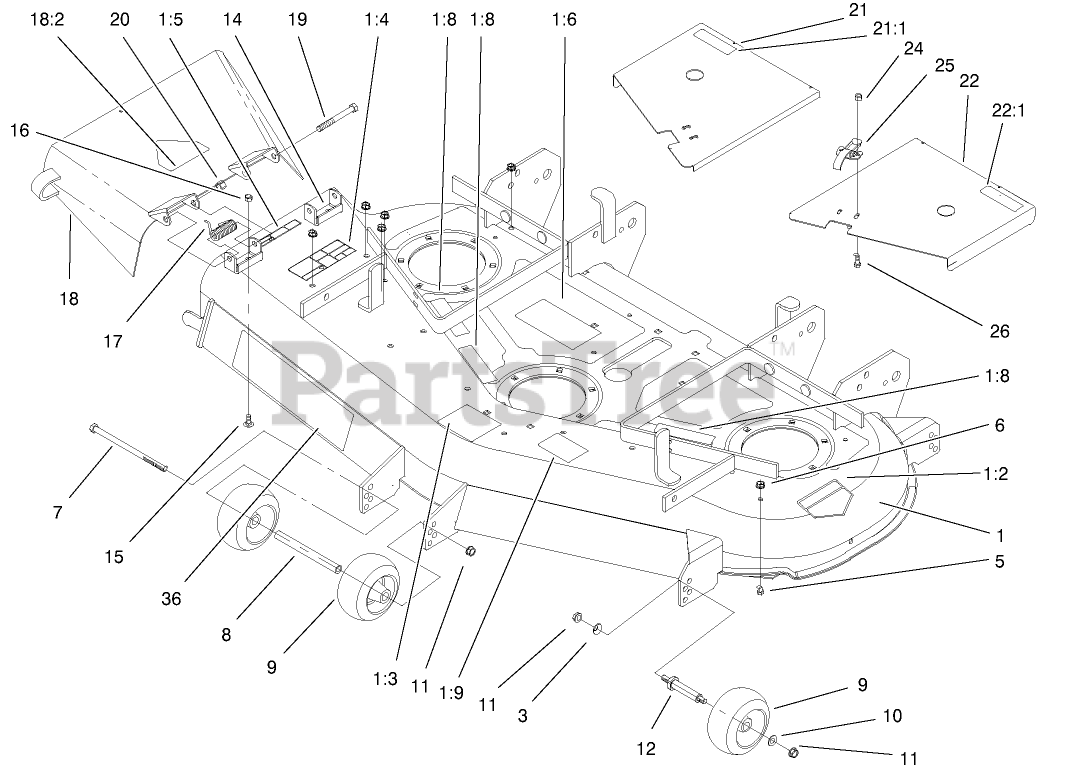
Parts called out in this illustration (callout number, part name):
1	52" Deck ASM
1:2	DECAL-DANGER
1:3	DECAL-WHEEL, GAGE
1:4	DECAL-DANGER, THROWN OBJECT
1:5	DECAL-DANGER
1:6	DECAL-BELT ROUTING
1:8	DECAL-COVER, MISSING
1:9	DECAL-TORQUE, BLADE BOLT
3	WASHER-BELLEVILLE
5	SCREW-HH
6	NUT-HF
7	SCREW-HH
8	SPACER-WHEEL
9	WHEEL-GAGE
10	Washer
11	NUT-HHF, WHIZ
12	SPACER
14	BRACKET-PIVOT
15	SCREW-CARR
16	NUT-LOCK, CONE
17	SPRING
18	DEFLECTOR ASM, 52" W/DECAL
18:2	DECAL-DANGER
19	SCREW-HH
20	NUT-HEX
21	COVER ASM-RH
21:1	DECAL-DANGER
22	LH COVER ASM
22:1	DECAL-DANGER
24	NUT-LOCK, FLANGE
25	CLAMP-SLOTTED
26	SCREW-HWH
36	DECAL
